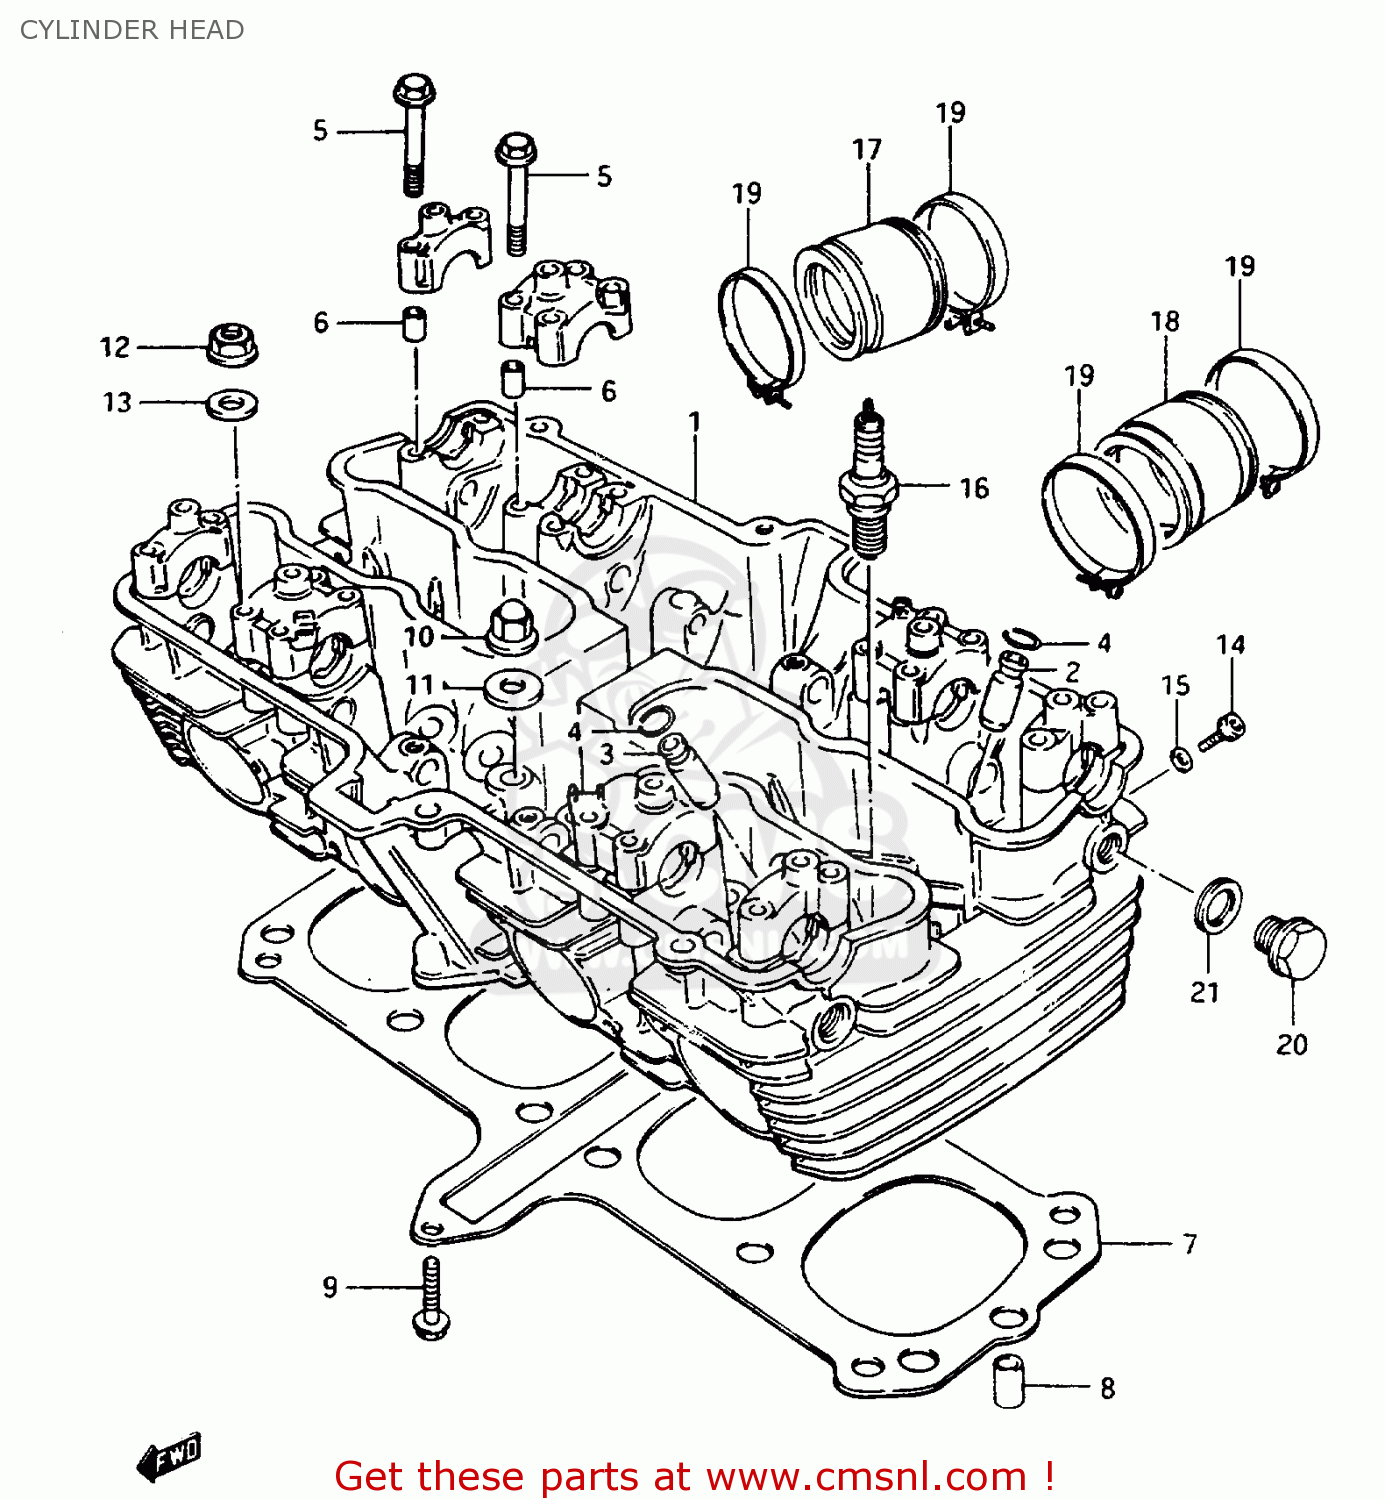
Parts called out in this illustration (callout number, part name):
1	HEAD,CYLINDER (16 VALVE)
2	GUIDE,INTAKE VALVE
3	GUIDE,INTAKE VALVE
4	RING,SNAP
5	BOLT(6X39)
6	PIN(6.2X8X11)
7	GASKET,CYLINDER HEAD (NAS)
8	PIN
9	BOLT 6X30
10	NUT
11	GASKET(10.5X22X2) (NAS)
12	NUT
13	WASHER(10.5X22X2.3)
14	BOLT, INTAKE PORT
15	GASKET(5.3X9.3X1.2) (NAS)
16	SPARK PLUG D9EA
17	PIPE,INTAKE RH
18	PIPE INTAKE (NAS)
19	CLAMP
20	PLUG (14X12)
21	GASKET(14X19.2X2) (NAS)
